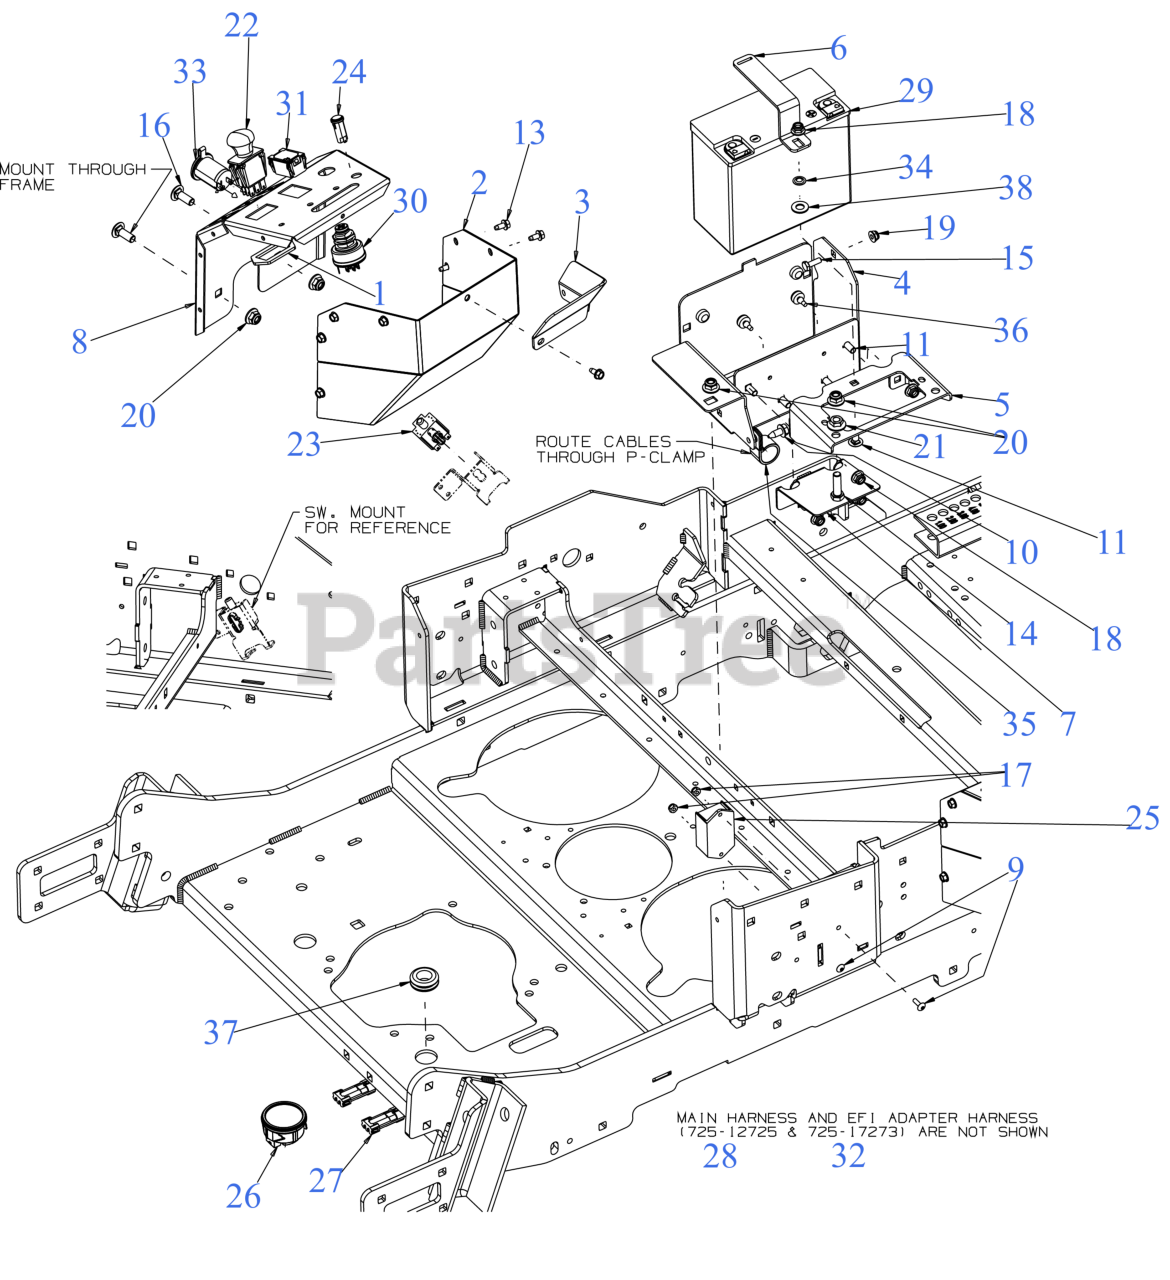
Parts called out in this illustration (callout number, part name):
1	BRACKET-PTO SWITCH
4	BATTERY MOUNT BRACKET
5	FUSE/RELAY MOUNT BRACKET
6	BATTERY SUPPORT BRACKET
7	HARNESS GUARD PLATE
8	CONTROL POD (RH)
9	SCREW #10-24 x .62
10	SCREW 5/16-18 x .750
11	CARRIAGE BOLT 5/16-18 x .75
12	CARRIAGE BOLT 3/8-16 X1.25 GR5
13	SCREW 1/4-20 X.500
14	SCREW 3/8-16 x 1.25 GR5
15	SCREW 1/4-20X.75 GR5
16	CARRIAGE BOLT 3/8-16 x 1.00 GR5
18	FLANGE LOCK NUT 5/16-18
19	FLANGE LOCK NUT
21	FLANGE LOCK NUT
22	PTO SWITCH (BLACK KNOB) TEXT SYM
23	3 POLE SWITCH ( NC-NO-NO)
24	INDICATOR LIGHT-RED
25	CONTROL PANEL (SOFT CLUTCH)
26	DUAL FUEL GAUGE
27	SEALED CAP ASSEMBLY
28	MAIN HARNESS
29	BATTERY (300 CCA)
30	KEY SWITCH
31	HOUR METER
32	ADAPTER HARNESS
33	POWER RECEPTICAL
35	HOSE CLAMP 1.0"
36	BUMPER, .62 DIA x .3
37	RUBBER GROMMET
38	FLAT WASHER
